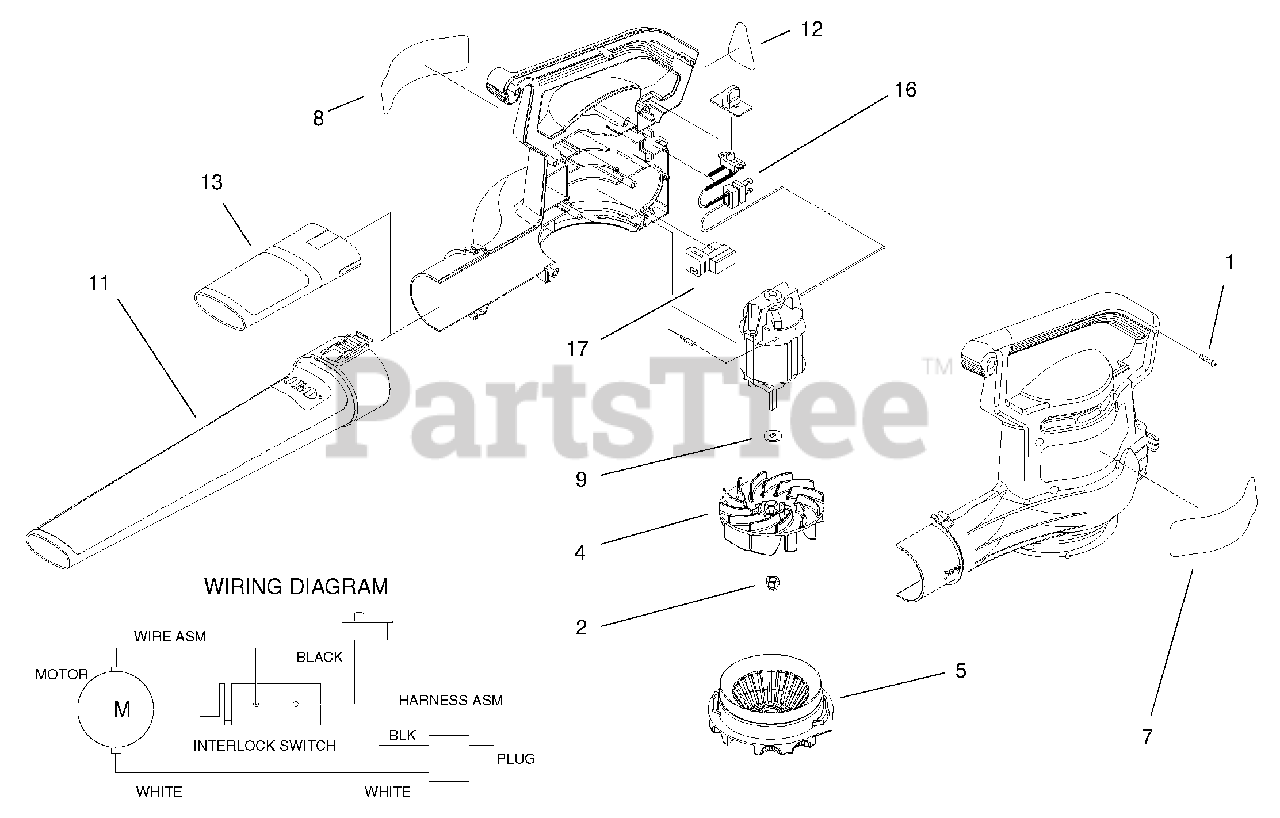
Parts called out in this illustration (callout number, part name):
1	Screw-PPH
2	Nut-Hex
4	Impeller-Blower
5	Inlet Cover & Decal ASM
7	Decal-Logo
8	Decal-Warning
11	Tube-Blower
12	Decal-Information
13	Insert-Tube
16	Wire Harness
17	Switch-Interlock
